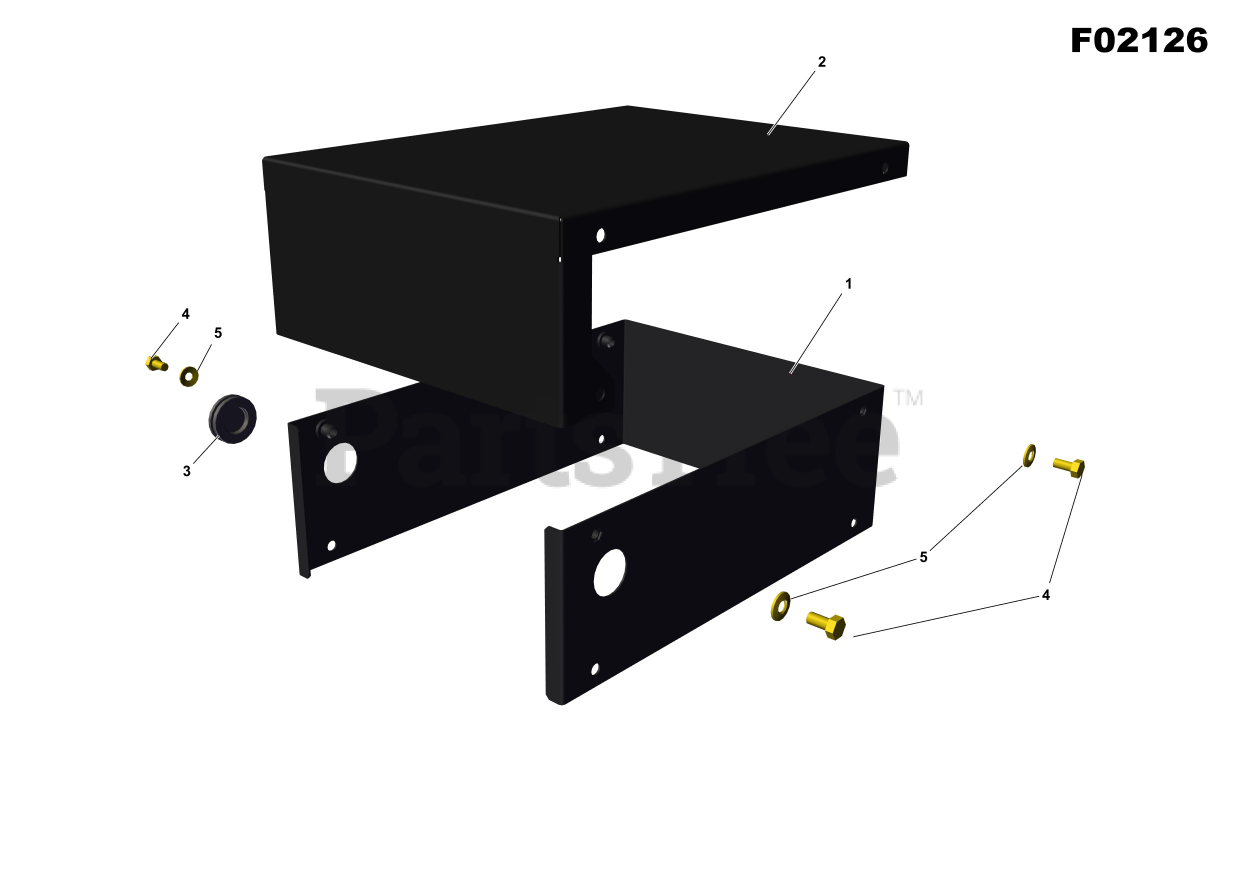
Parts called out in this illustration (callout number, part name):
1	Alternator cover
2	Alternator cover
4	Screw H M5x10
5	Washer CS D5x12
